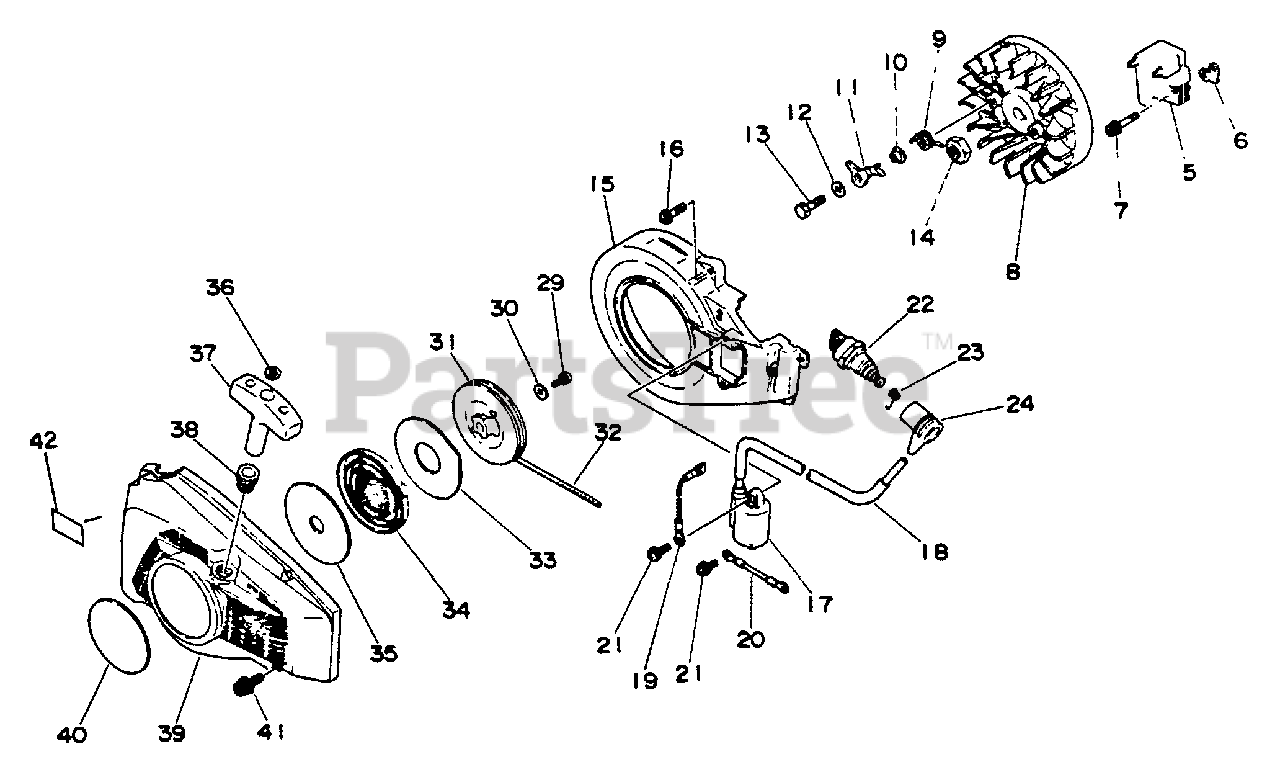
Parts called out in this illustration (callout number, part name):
5	COIL, IGNITION
7	SCREW 4×22
8	FLYWHEEL
10	SPACER
11	RATCHET
12	WASHER 5.5×12×0.8
13	BOLT - 5×20
15	SHIELD, FAN
16	SCREW 4×20
17	COIL, IGNITION
18	PIPE
19	LEAD
20	LEAD - GROUND
21	SCREW 4×14
22	SPARK PLUG - CJ-7Y
23	TERMINAL, SPARK PLUG
24	CAP, SPARK PLUG
29	SCREW 5×10
30	WASHER 5.5×12×0.8
31	REEL, ROPE
32	ROPE, STARTER 4.0×950
33	PLATE, SIDE
34	SPRING, RECOIL
35	PLATE, STARTER
38	GUIDE, ROPE
39	CASE, STARTER
40	LABEL - ECHO
41	BOLT 5×20
42	LABEL - NOISE
